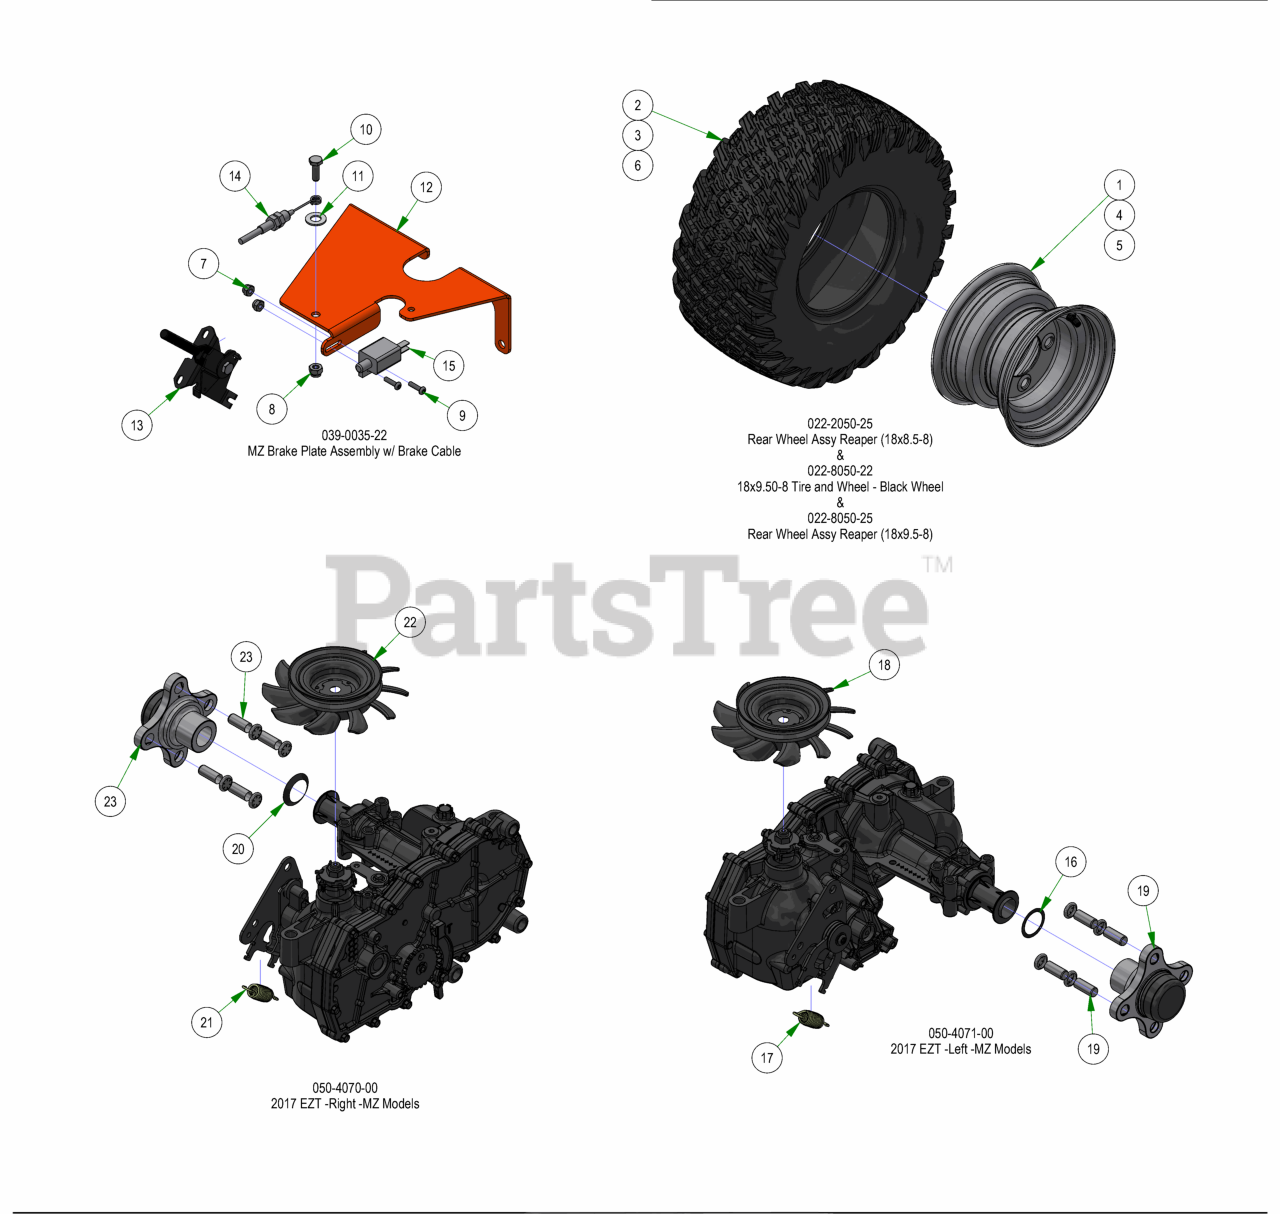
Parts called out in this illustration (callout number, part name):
1	Rim for 022-2050-22 / 022-2050-25
2	Tire Only for Rear Wheel Assy Reaper (18x8.5-8)
3	18x9.50-8 Rear Tire Only 48 MZ
4	Black Rear Wheel 48in MZ
5	Wheel Only for Rear Wheel Assy Reaper (18x9.5-8)
6	Tire Only for Rear Wheel Assy Reaper (18x9.5-8)
7	#10 Nylock Nut
8	1/4-20 NYLON INSERT LOCKNUT ZINC
9	10-24 X 5/8 BS Button Head Bolt
10	1/4-20 X 3/4 HEX CAP SCREW (GR.5) ZINC
11	.390 ID X .750 OD X .062 THK FLAT WASHER NYLON
12	2017 MZ Brake Lock Bracket
13	Universal Throttle Head - 2012
14	MZ Brake Cable
15	Safety Switch
16	MZ Seal & Retainer Kit
17	Transaxle Spring
18	Fan/Pulley Kit for ZT / 2017 MZ
19	MZ 4 Bolt Hub Kit
20	MZ Seal & Retainer Kit
21	Transaxle Spring
22	Fan/Pulley Kit for ZT / 2017 MZ
23	MZ 4 Bolt Hub Kit
